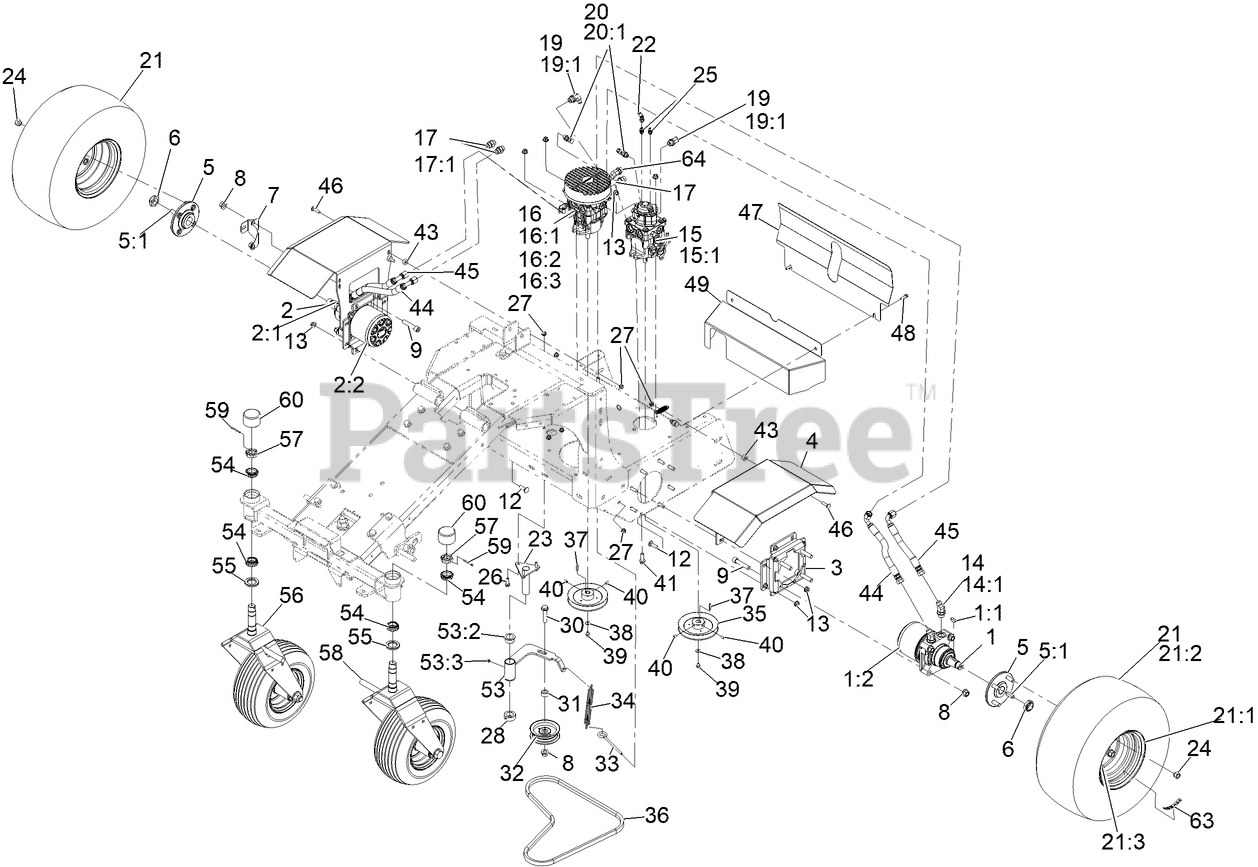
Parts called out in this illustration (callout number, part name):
1	MOTOR-WHEEL, LH
1:1	KEY-WOODRUFF
1:2	SEAL KIT
2	MOTOR-WHEEL, RH
2:1	KEY-WOODRUFF
2:2	SEAL KIT
3	X-REF 142-0270-05
4	FENDER-AE
5	HUB-WHEEL
5:1	STUD-1/2-20 X 1.55
6	LOCKNUT
7	BRACKET-HOPPER, SPEEDOMET
8	Nut-Lock 1/2-13
9	Screw-HSH
12	BOLT-CARR
13	NUT-HF, NI
14	FITTING-ELBOW, 45 DEG
14:1	O-RING
15	PUMP-HYD,LH,W/ AUX,ZPLUG,
15:1	SPRING-EXTENSION
16	PUMP-HYD, RH,W/ FAN ZPLUG
16:1	SPRING-EXTENSION
16:2	HYDRO PUMP FAN
16:3	GUARD-PUMP
17	FITTING-STRAIGHT
17:1	O-RING
19	FITTING-ELBOW, 90 DEG
20	FITTING-ELBOW, 90 DEG
20:1	O-RING
21	WHEEL AND TIRE ASM
21:1	Rim-8 X 7, Black
21:3	Stem-Valve
22	4MJIC-4FJIC 90 DEG SWIVEL
23	PIVOT-IDLER
24	NUT-LUG
25	FITTING-STRAIGHT
26	SCREW-HH
27	NUT-HF, NI
30	Screw-HHF
32	PULLEY-IDLER, FLAT
33	5/16-18 X 6 EYE BOLT W/ 5
34	SPRING-EXTENSION
35	PULLEY, DRIVE, 5-5/8" 17M
36	B54 BELT 2011+ ZPLUG (16C
39	SCREW-HHF
40	Setscrew-HSH
41	SCREW-HHF
44	Hose ASM-HYD HP
45	Hose ASM-HYD HP
46	Bolt-Carriage 5/16-18 X 1 1/4
47	GUARD-PUMP
48	SCREW-HHF
53	ARM-IDLER, ASM
53:2	BUSHING-FLANGE
53:3	FITTING-GREASE, ZERK
54	CONE-BEARING, OUTER
55	SEAL-GREASE
56	Caster ASM - RH
57	NUT-SHH
58	Caster ASM - LH
59	Pin-Cotter
60	CAP-DUST, RUBBER
63	DECAL-TORQUE, WHEEL HUB LUG
64	FITTING-ELB 90
